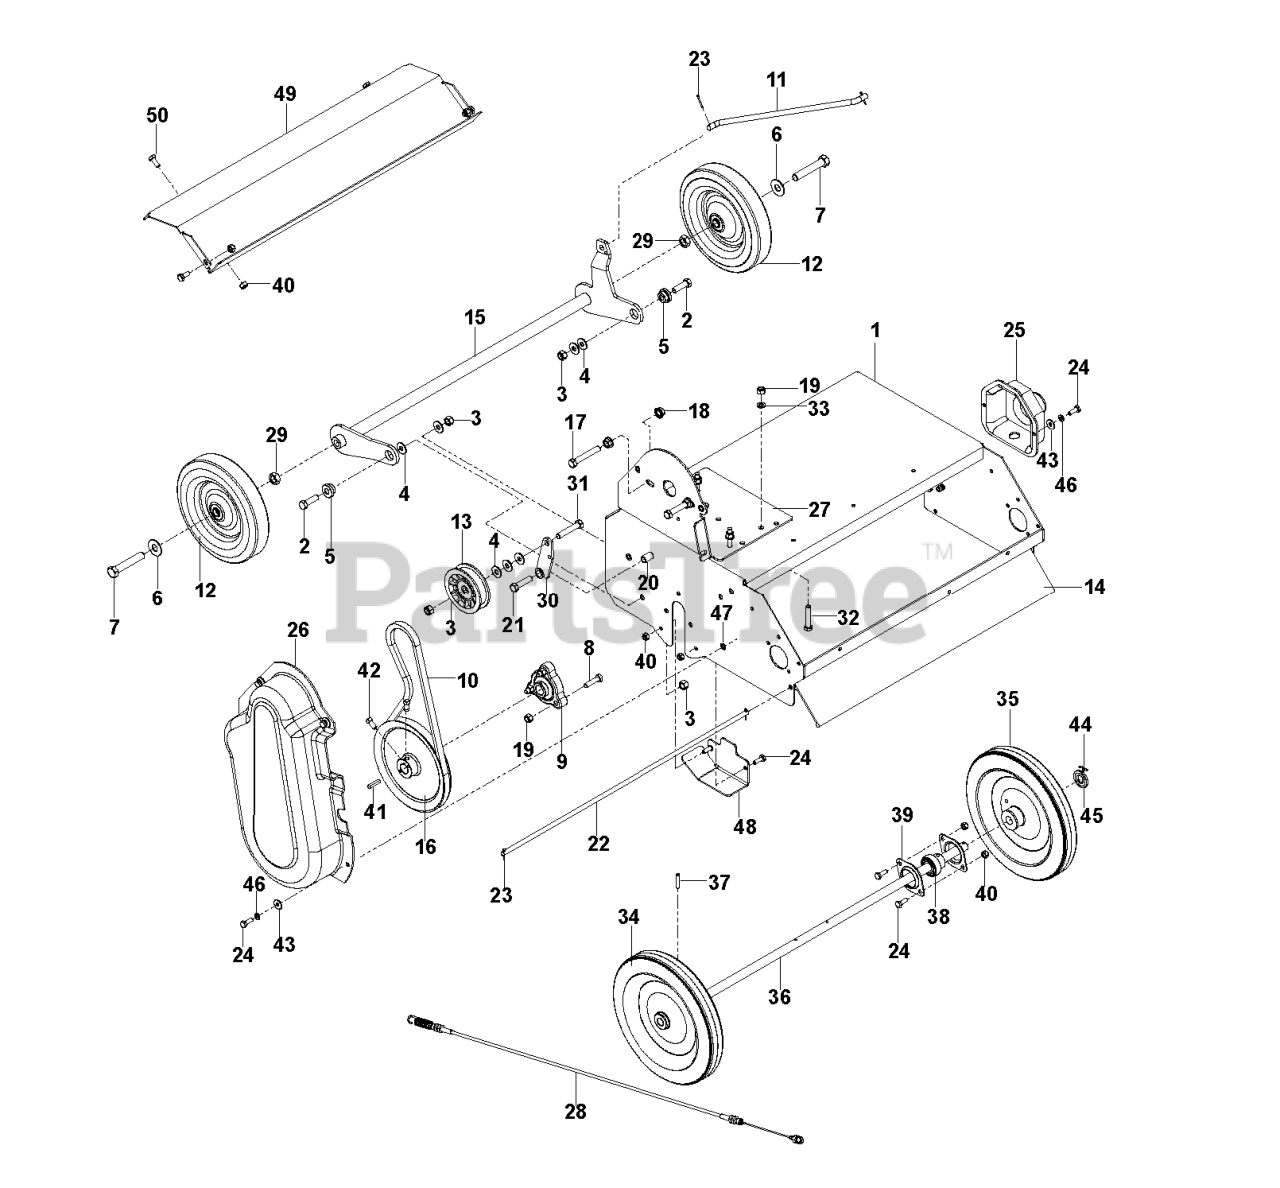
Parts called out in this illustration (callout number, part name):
1	WLDMT, BODY - ORANGE DT22
2	HCS 3/8C X 1 1/4 GR5
3	NUT 3/8-16 NYLOC
4	WASHER 5/16 FLAT
5	BUSHING RAKE
6	WASHER 1/2 FLAT
7	HCS 1/2C X 2 3/4
8	HCS 5/16C X 1 1/4
9	BEARING, FLANGED
10	BELT, DRIVE RAKE/SLICER DFS
12	WHEEL 8 X 1 3/4 RAKE
13	PULLEY, IDLER RAKE & ZTR
15	FRONT AXLE
16	PULLEY, MAIN SHAFT
17	HCS 3/8C X 2 1/2
18	NUT 3/8C WHIZ
19	NUT 5/16 NYLOC
20	BEARING, ONLITE RAKE/DT
21	HCS 3/8C X 1 1/2
23	COTTER PIN 3/32 X 3/4
24	HCS 1/4C X 3/4 HCS
25	SHAFT GUARD
26	BELT SHIELD POWER RAKE
27	BACKING PLATE ORANGE
28	CABLE POWER RAKE
29	NUT 1/2 HEX JAM
30	IDLER ARM - ORANGE
31	HCS 3/8C X 2
32	HCS 5/16C X 1 3/4
33	WASHER.LOCK.HVY.HLCL.SPR.5/16
34	WHEEL 10 X 1 3/4
35	WHEEL 10 X 1 3/4
36	AXLE, REAR
37	PIN ROLL 1/4 X 1-1/8
38	BEARING - 5/8" W/COLLAR
39	FLANGE BEARING ZINC PLATED
40	NUT.1/4-20.HEX.NYLOC.ZD
41	KEY, 3/16 SQUARE
42	SET SCREW 5/16 NYLOC
43	WASHER 1/4 FLAT
44	COTTER PIN
45	WASHER 5/8 FLAT
46	LOCKWASHER 1/4"
47	KNURLED INSERT
48	SKID PLATE
49	REAR COVER ORANGE
50	HCS 1/4C X 5/8
